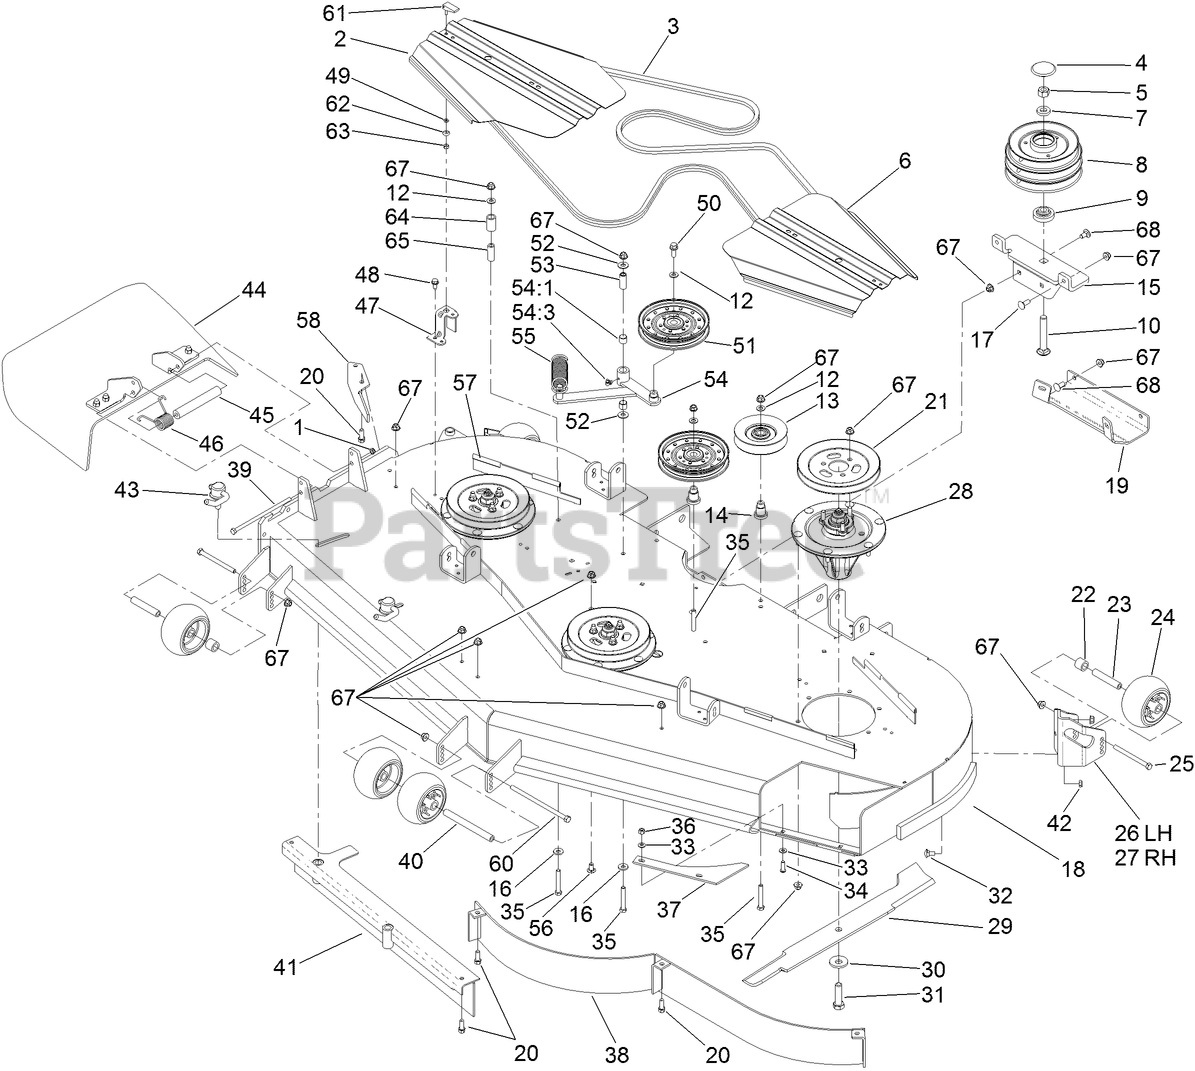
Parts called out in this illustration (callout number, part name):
1	NUT-LOCK, NI
2	COVER-BELT, LH
3	BELT-V
4	CAP-PLASTIC
5	NUT-HEX
6	COVER-BELT, RH
7	SPACER
8	PULLEY AND BEARING ASM
9	SPACER-FLANGED
10	BOLT-CARRIAGE
12	WASHER-FLAT
13	PULLEY-IDLER
14	MOUNT-PULLEY
15	MOUNTING BRACKET ASM
16	WASHER-BELLEVILLE
17	SCREW-HH
18	DECK DECAL ASM
19	PLATE-SKID
21	PULLEY
22	TUBE-SPACER
23	TUBE-SPANNER
24	ROLLER-SCALP, ANTI
25	SCREW-HH
26	MOUNT-WHEEL, LH
27	MOUNT-WHEEL, RH
28	SPINDLE ASM
29	BLADE-HI FLOW, 24.5 INCH
30	WASHER-BLADE BOLT, HEAVY
31	SCREW-BLADE
32	SCREW-HH
33	WASHER-SPRING
34	SCREW-HSBH
35	SCREW-HH
36	NUT-LOCK, NI
37	PLATE-TURBO
39	SCREW-HH
40	SPACER-WHEEL
43	LEVER ASM
44	RUBBER DEFLECTOR ASM
45	SPACER
46	SPRING-TORSION
47	BRACKET-COVER
48	SCREW-HWHTF
49	WASHER
50	SCREW-HHF
52	WASHER-FLAT
53	BUSHING
54	IDLER ARM ASM
54:1	SLEEVE-BEARING
54:3	FITTING-GREASE, 90 DEG
55	SPRING-EXTENSION
56	SCREW-CARR
57	STRIP-SEAL
58	BAFFLE-DISCHARGE
60	SCREW-HH
61	HANDLE-LATCH, SWELL
62	BUSHING-LATCH, SWELL
63	NUT-LOCK, HH
64	SPACER-RUBBER
65	SPACER-PIVOT, IDLER
67	NUT-HF, NI
68	SCREW-CARR
